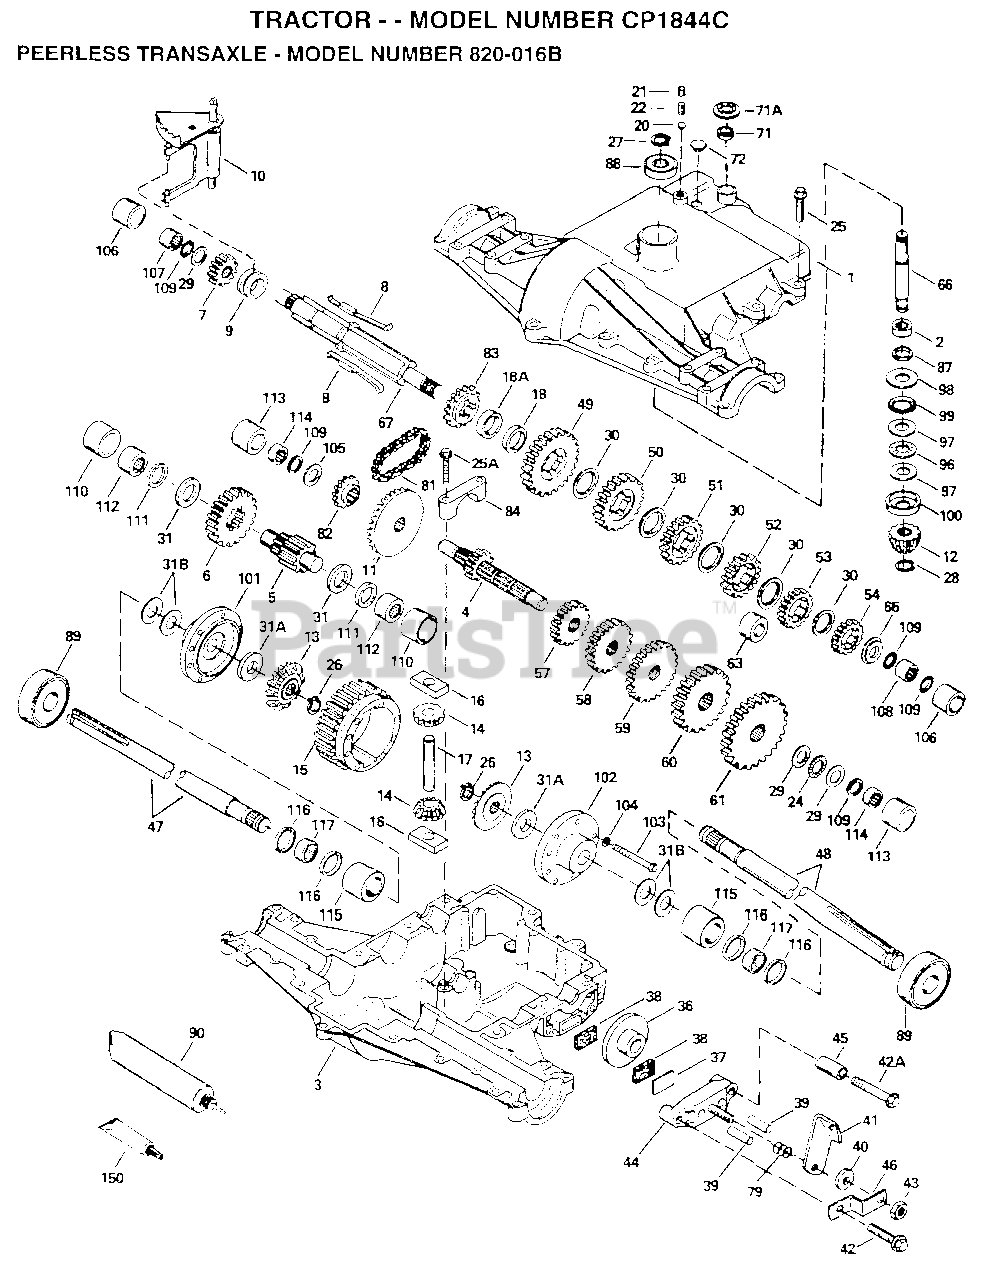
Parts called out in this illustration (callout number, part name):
1	COVER TRANSAXLE
2	BEARING NEEDLE
3	CASE TRANSAXLE
4	SHAFT COUNTER
5	SHAFT, OUTPUT, 9T
6	GEAR, OUTPUT, 35T
7	GEAR, SPUR, 15T
9	COLLAR SHIFT
10	ROD AND FORK ASSY SHIFT
11	GEAR BEVEL, 33T
12	BEVEL PINION, 13T
14	PINION, 10T
15	GEAR, RING, 31T
16	BLOCK DRIVE
18	SPACER, .350/.340 THICK
18A	SPACER, .276/.268 THICK
20	BALL STEEL, 5/16" DIA.
21	SCREW, 3/8-16 X 3/8"
24	THRUST BEARING
25	SCREW HEX HD 5/16-18 X 1-1/4
25A	SCREW, 1/4-20 X 1-1/4
28	RETAINING RING
29	WASHER THRUST
30	WASHER THRUST
31	WASHER THRUST
31B	WASHER THRUST
37	PLATE BRAKE PAD
41	LEVER BRAKE
42	SCREW, 1/4-20 X 1-1/4
42A	SCREW, 1/4-20 X 2-1/4
43	LOCKNUT 5/16-24
44	HOLDER BRAKE PAD
46	BRKT BRAKE LEVER
47	AXLE, 12-5/16" LONG
48	AXLE, 16-3/16" LONG
49	GEAR, SPUR, 41T
50	GEAR, SPUR, 35T
51	GEAR, SPUR, 30T
52	GEAR, SPUR, 25T
53	GEAR, SPUR, 22T
54	GEAR, SPUR, 19T
57	GEAR, SPUR, 15T
58	GEAR, SPUR, 20T
59	GEAR, SPUR, 25T
60	GEAR, SPUR, 28T
61	GEAR, SPUR, 31T
66	SHAFT INPUT
67	SHAFT BRAKE
71	SEAL SQUARE CUT
72	PLUG, THRDED, 9/16-18
81	CHAIN, ROLLER
82	SPROCKET 9T
83	SPROCKET 18T (REV)
84	BEARING CAP
87	OIL SEAL 3/4
88	BEARING BALL
89	BEARING BALL
90	GREASE BENTONITE, 32 OZ.
96	BEARING THRUST
97	WASHER THRUST
100	WASHER CUPPED
101	CARRIER DIFF THREADED HOLES
102	CARRIER DIFF
103	SCREW, 1/4-20 X 2-1/4
104	WASHER LOCK 1/4
107	BEARING NEEDLE
108	BEARING NEEDLE
110	SLEEVE STEPPED
111	RING SQ CUT
112	BEARING NEEDLE CAPPED
113	SLEEVE STEPPED
114	BEARING NEEDLE CAPPED
115	SLEEVE STEPPED
116	RING SQ CUT
117	BEARING NEEDLE
150	GASKET ELIMINATOR
